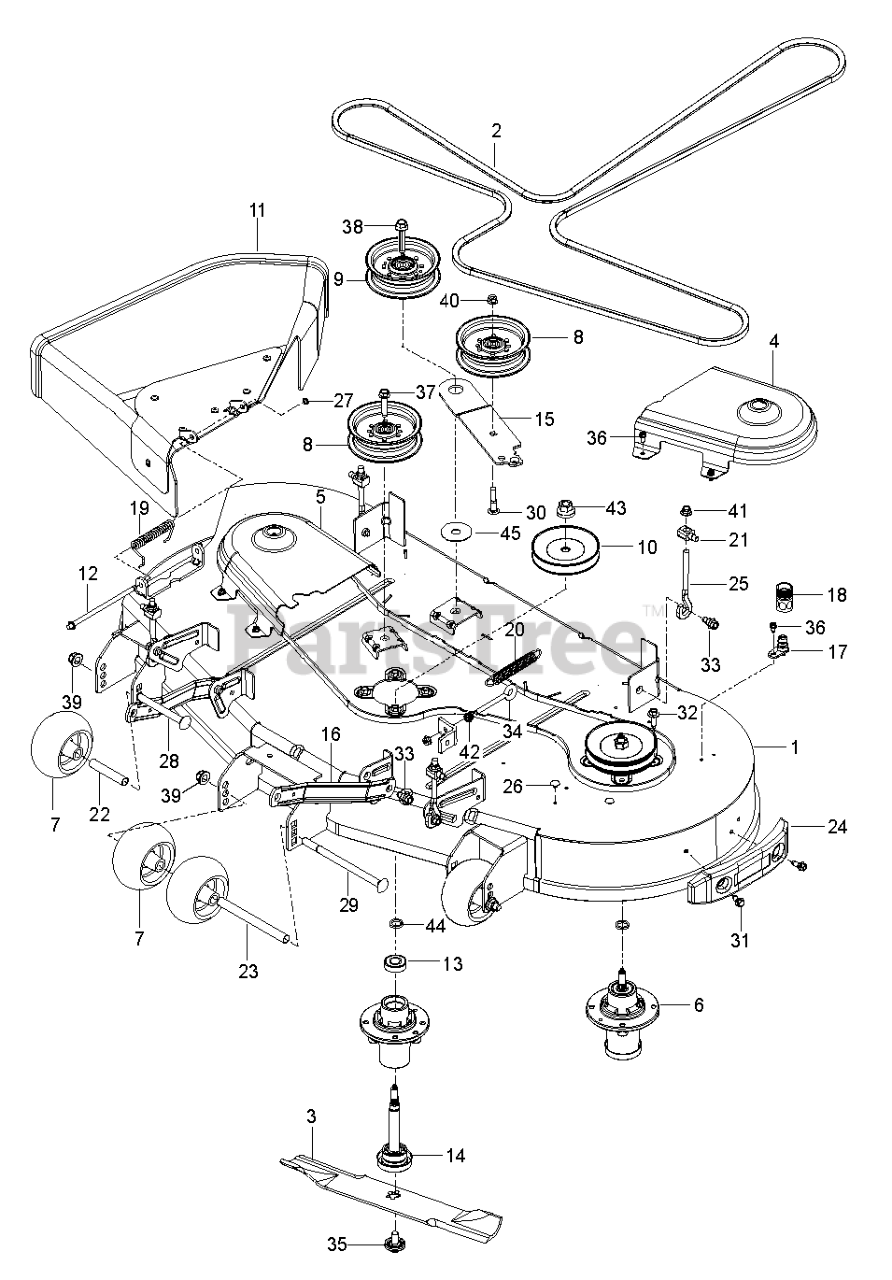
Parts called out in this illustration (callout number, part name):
1	DECK.SVC.54.CLRCT.MZ.MS668
2	BELT CLEARCUT 54, MZ DECK DRIV
3	BLADE CC54 PZ STYLE HIGH LIFT,
4	COVER.PNT.54CC.MNDRL.LH.ZTR.GY
5	COVER 54 CLEARCUT RH MANDREL G
6	MANDREL ASM, CAST IRON
7	ROLLER, GAUGE .635 BORN
8	PULLEY.IDLER.2006
9	RB PULLEY.IDLER.4.50/HUB SPEC
10	PULLEY.MANDREL.CRD 107CM.DOM.
11	DEFLECTOR ASSY 54 CLEARCUT RES
12	ROD.HINGE
14	SHAFT ASM MANDREL
15	ARM IDLER ARM, CLEARCUT 54 BLA
16	ARM.RFIXED.MOWER.SUSPNSIONX431
17	PORT.WASHOUT
18	COUPLING.QUICK CONNECT
19	SPRING.42.FCS.DEFLECTOR
20	SPRING.MOWER.DRIVE.ELECTRIC
22	TUBE, ROLLER AXLE
23	TUBE, ROLLER AXLE LONG
24	BUMPER ASSY 54 CLEARCUT TRIM S
25	LINK.ASM.ADJUSTABLE
26	PLUG CHRISTMAS TREE
27	NUT PUSH M
28	RHSNB 1/2-13 X 4.75 GR5 ZD
29	RHSNB 1/2-13 X 8 GR5 ZD
31	SHOULDER BOLT 5/16-18TT
32	BOLT.HEX.WASHR.HED.313-18X1.19
33	BOLT.SHOULDER
34	EYE BOLT 5/16 X 3.50
35	BOLT.WASHER.ASM.7/16-2
36	SCREW.1/4-20X5/8
37	SCREW LT
38	SCREW.7/16-14 X 2.125.WASHER
39	NUT, 1/2-13 HEX FLG NYLOC ZD
40	NUT LOCK FLG 3/8-16 UNC
41	NUT.HEX.FLANGE.INS.BLK.3/8-16
42	NUT 5/16C WHIZ
43	NUT.FLANGE.LOCK.TOP
44	WASHER.SPACER.MANDREL
